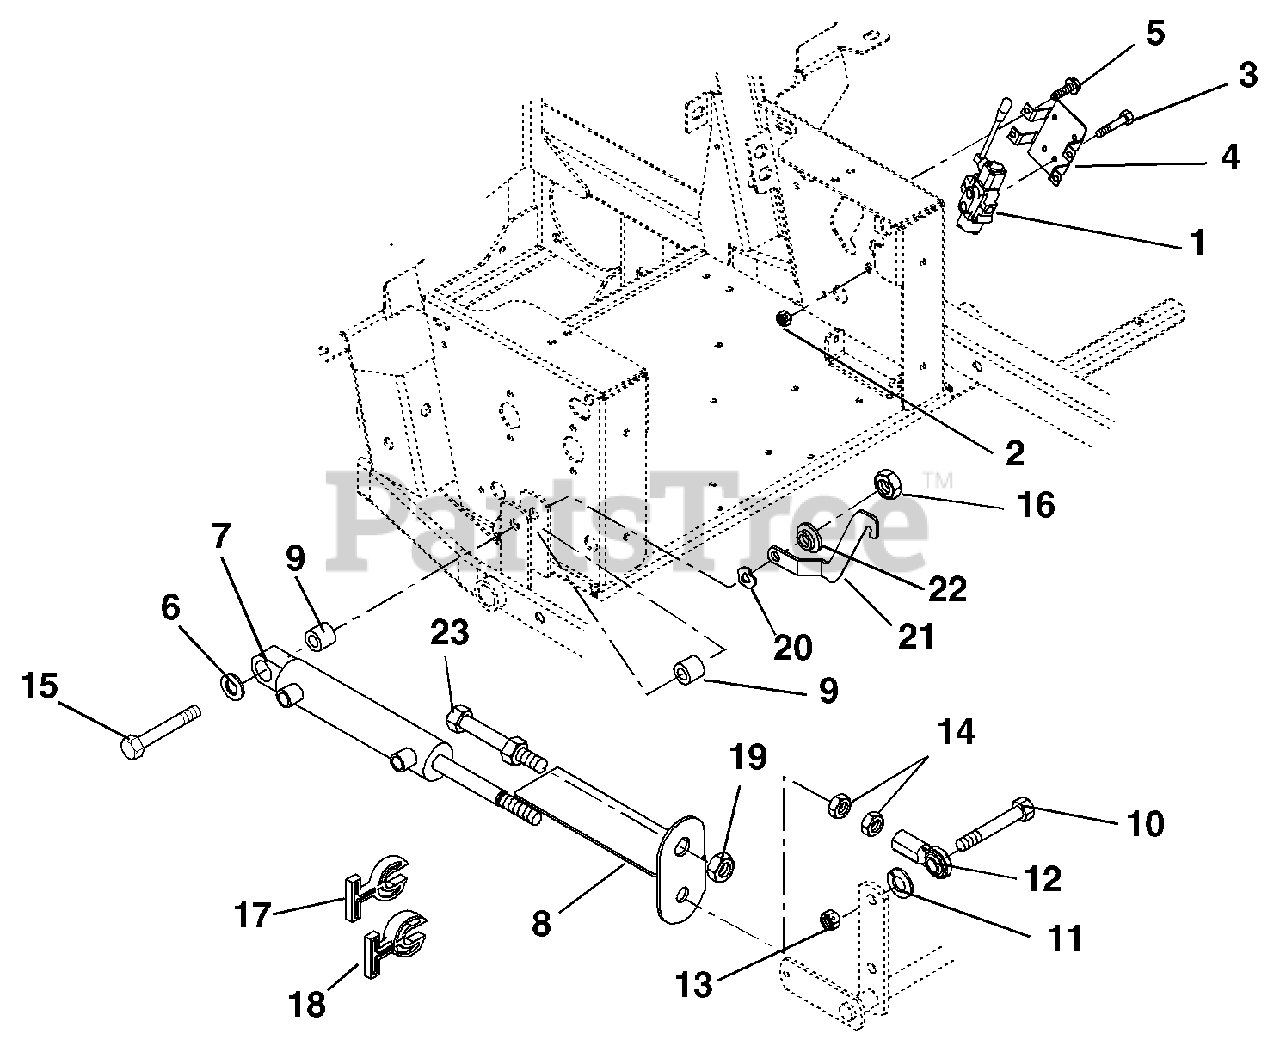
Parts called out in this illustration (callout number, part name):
1	Valve, Hydraulic
2	Nut, Locking Top Flange .31-18
3	Bolt, Hex .31-18 x 2.50 Grade 5
4	Bracket, Valve Mounting
5	Screw-Tapping .38-16 x .50 Hex Washer Head
6	Washer-Flat-Steel .515 x 1.625 x .25
7	Cylinder-Lift
8	Strap-Height of Cut Indicator
9	Bushing .516 x 1.00 x 1.05
10	Bolt-Hex .62-11 x 2.25 Grade 8
11	Washer-Lock .62 x .156
12	Rod End-Right Hand-Female .625
13	Nut-Locking-Center .62-11
14	Nut-Jam .625-18
15	Bolt-Hex .50-13 x 3.75 Grade 5
16	Nut, Locking Top Flange .50-13
17	Stop, Cylinder .34 Thick
18	Stop, Cylinder .68 Thick
19	Nut, Jam Center Lock .75-16
20	Washer, Wave .076 x 1.12 x .08
21	Latch, Floor Board
22	Bushing-Flange .515 x .75 x .275 x 1.12
